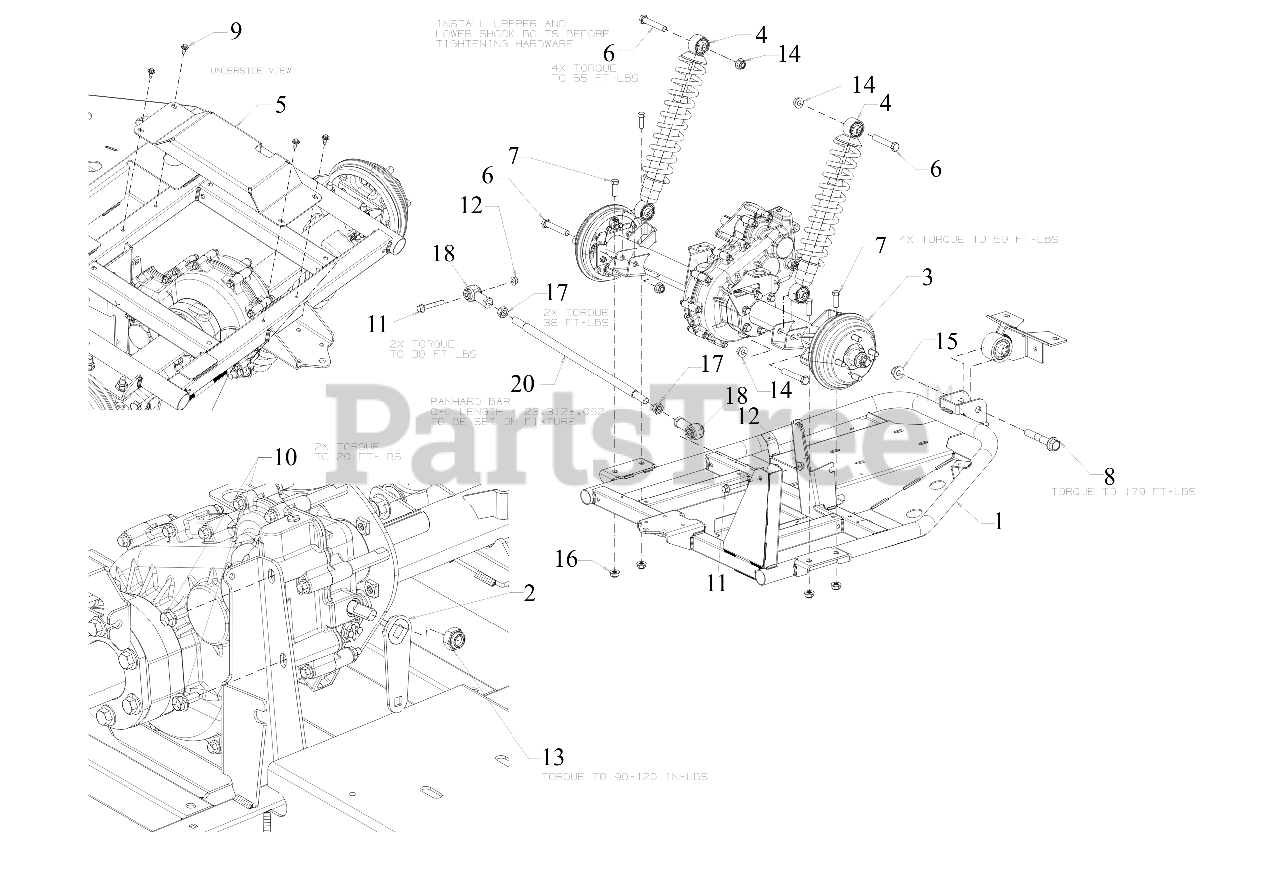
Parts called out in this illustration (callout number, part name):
2	TRANSAXLE SHIFT LINKAGE
3	REAR TRANSAXLE ASSEMBLY
4	REAR SHOCK ABSORBER
5	TRANSMISSION SHIELD BRACKET
6	SCREW-HEX 1/2-13 x 3.00
7	HEX SCREW 7/16-14 x 1.25
8	HEX FLANGE BOLT 5/8-11:3.75
9	SCREW M6-1 x .625
10	HEX FLANGE BOLT 5/16-24:0.75
11	HEX FLANGE BOLT 5/16-16:2.5
15	FLANGE LOCK NUT
16	HEX FLANGE LOCK NUT 7/16-14
17	HEX JAM NUT 5/8-18
18	BALL JOINT 5/8 x 5/8-18 x 1.5
20	PANHARD ROD
